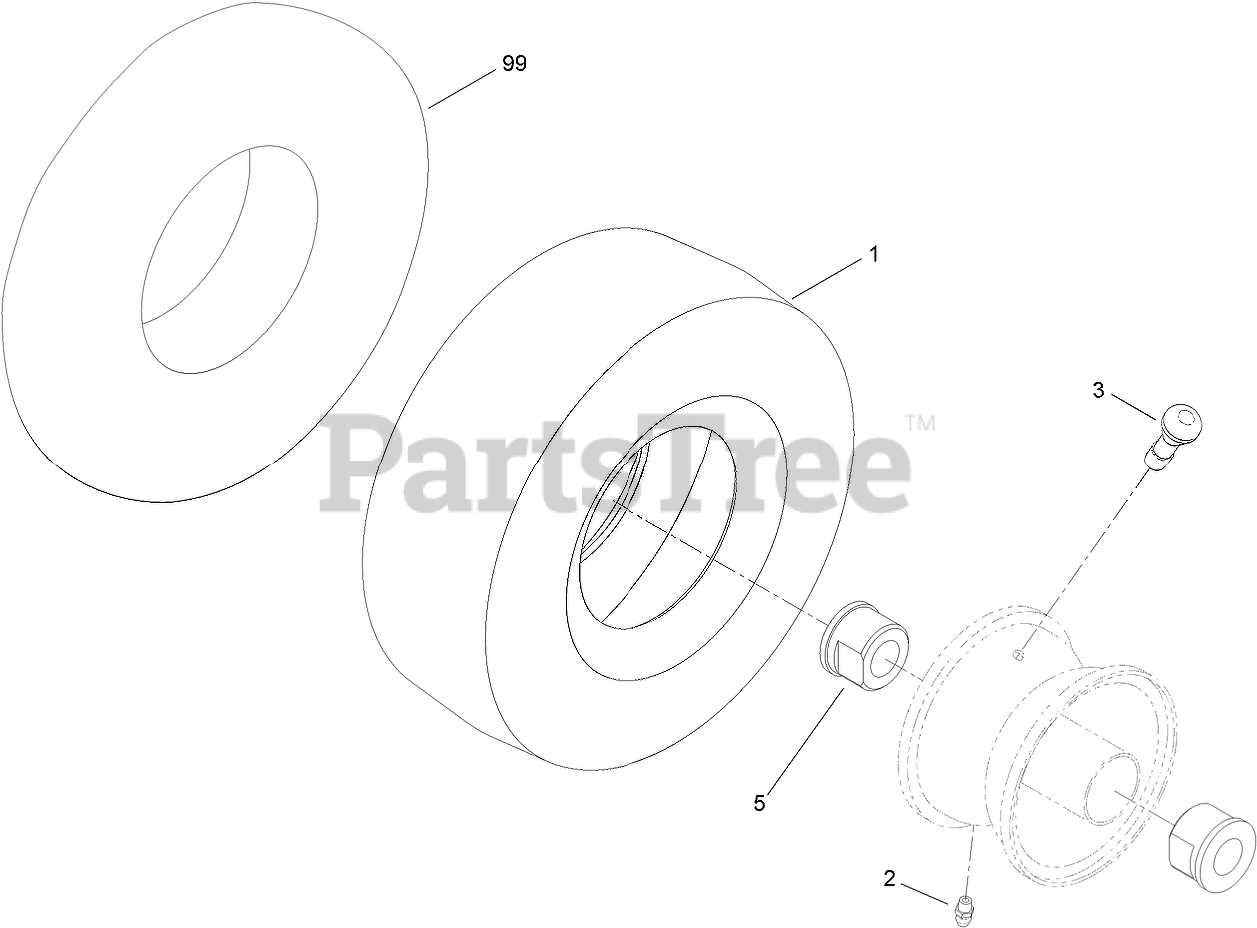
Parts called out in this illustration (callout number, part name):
1	TIRE-SMOOTH (Kenda)
2	FITTING-GREASE
3	STEM-VALVE
5	BUSHING-FLANGE
99	TUBE-INNER (W/VALVE)
